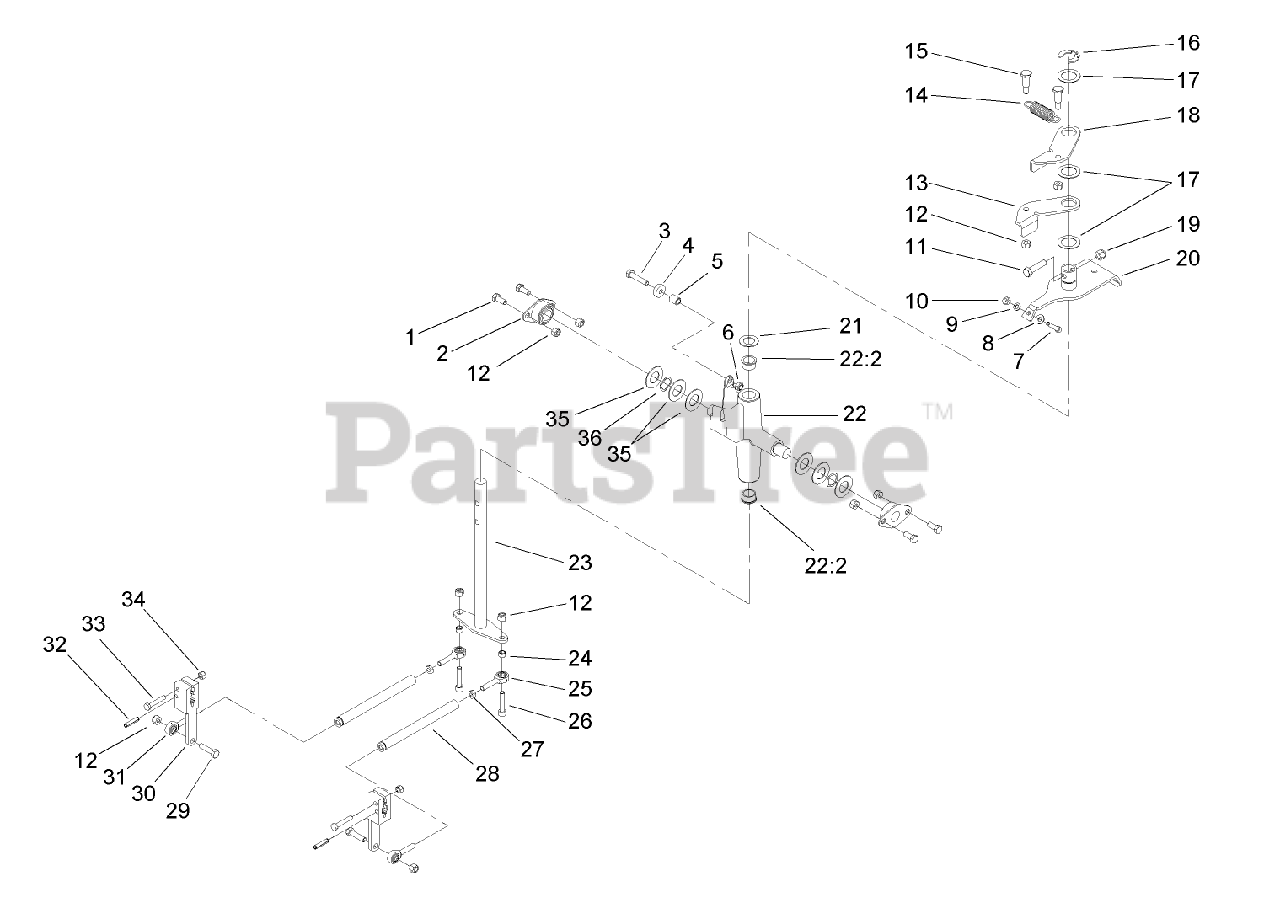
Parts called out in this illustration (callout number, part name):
1	SCREW-HH
2	BUSHING
3	SCREW-HH
4	BEARING-BALL
5	SPACER-LEVER, CONTROL
6	NUT-LOCK, NI
7	SCREW-HSH
8	WASHER-FLAT
9	WASHER-LOCK
10	NUT-HEX
11	SCREW-HH
12	NUT-LOCK, NI
13	LEVER-RETURN, RH
14	SPRING-EXTENSION
15	SCREW-SHOULDER
16	RING-RETAINING
17	WASHER-FLAT
18	LEVER-RETURN, LH
19	NUT-LOCK, NI
20	PIVOT LEVER ASM
21	WASHER-THRUST
22	CONTROL SUPPORT ASM
22:2	BEARING-FLANGE
23	DRIVE ROD ASM
24	SPACER-LEVER, TRACTION
25	BEARING-ROD END, RH
26	SCREW-HSH
27	NUT-JAM
28	ROD-LINKAGE
29	SCREW-HH
30	ARM-CONTROL, PUMP
31	BEARING-ROD END, LH
32	PIN-SPRING, SLOTTED
33	SCREW-HH
34	NUT-LOCK, NI
35	WASHER-FLAT
36	WASHER-SPRING, WAVE
